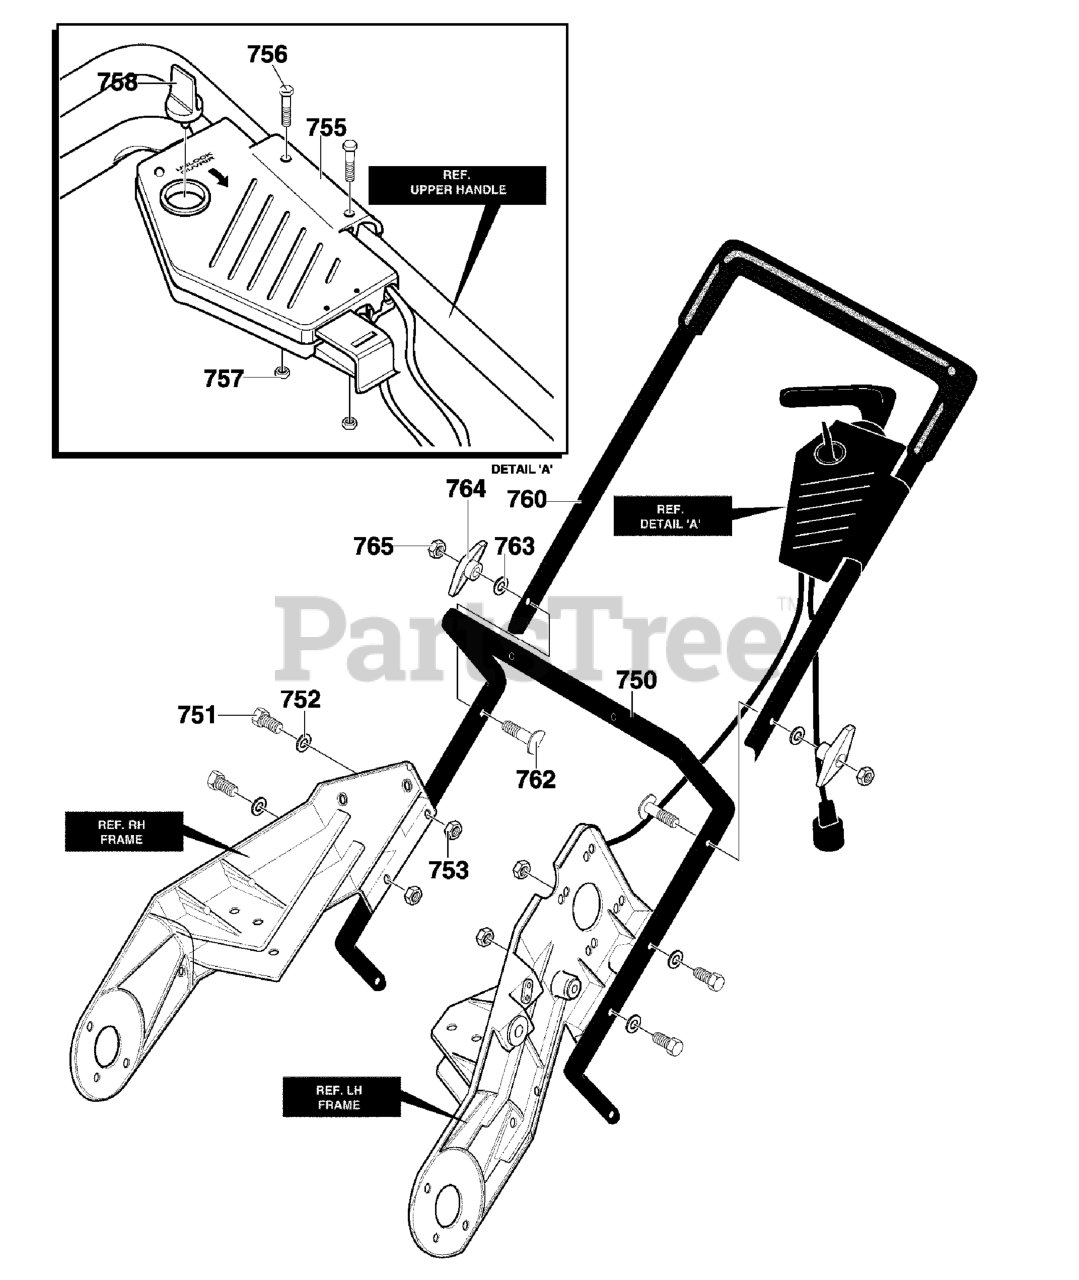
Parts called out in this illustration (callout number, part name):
750	HANDLE, LOWER
751	SCREW, 1/4-20 x 1.25
752	FLATWASHER
753	NUT, 1/4-20
755	ASSY, SWITCH BOX
756	SCREW, 10-24
757	NUT, #10-24
758	KEY, SWITCH BOX
760	UPPER HANDLE ASSY.
762	BOLT, 5/16-18 x 2.00
763	WASHER, FORMED
764	T KNOB
765	NUT, 5/16-18
